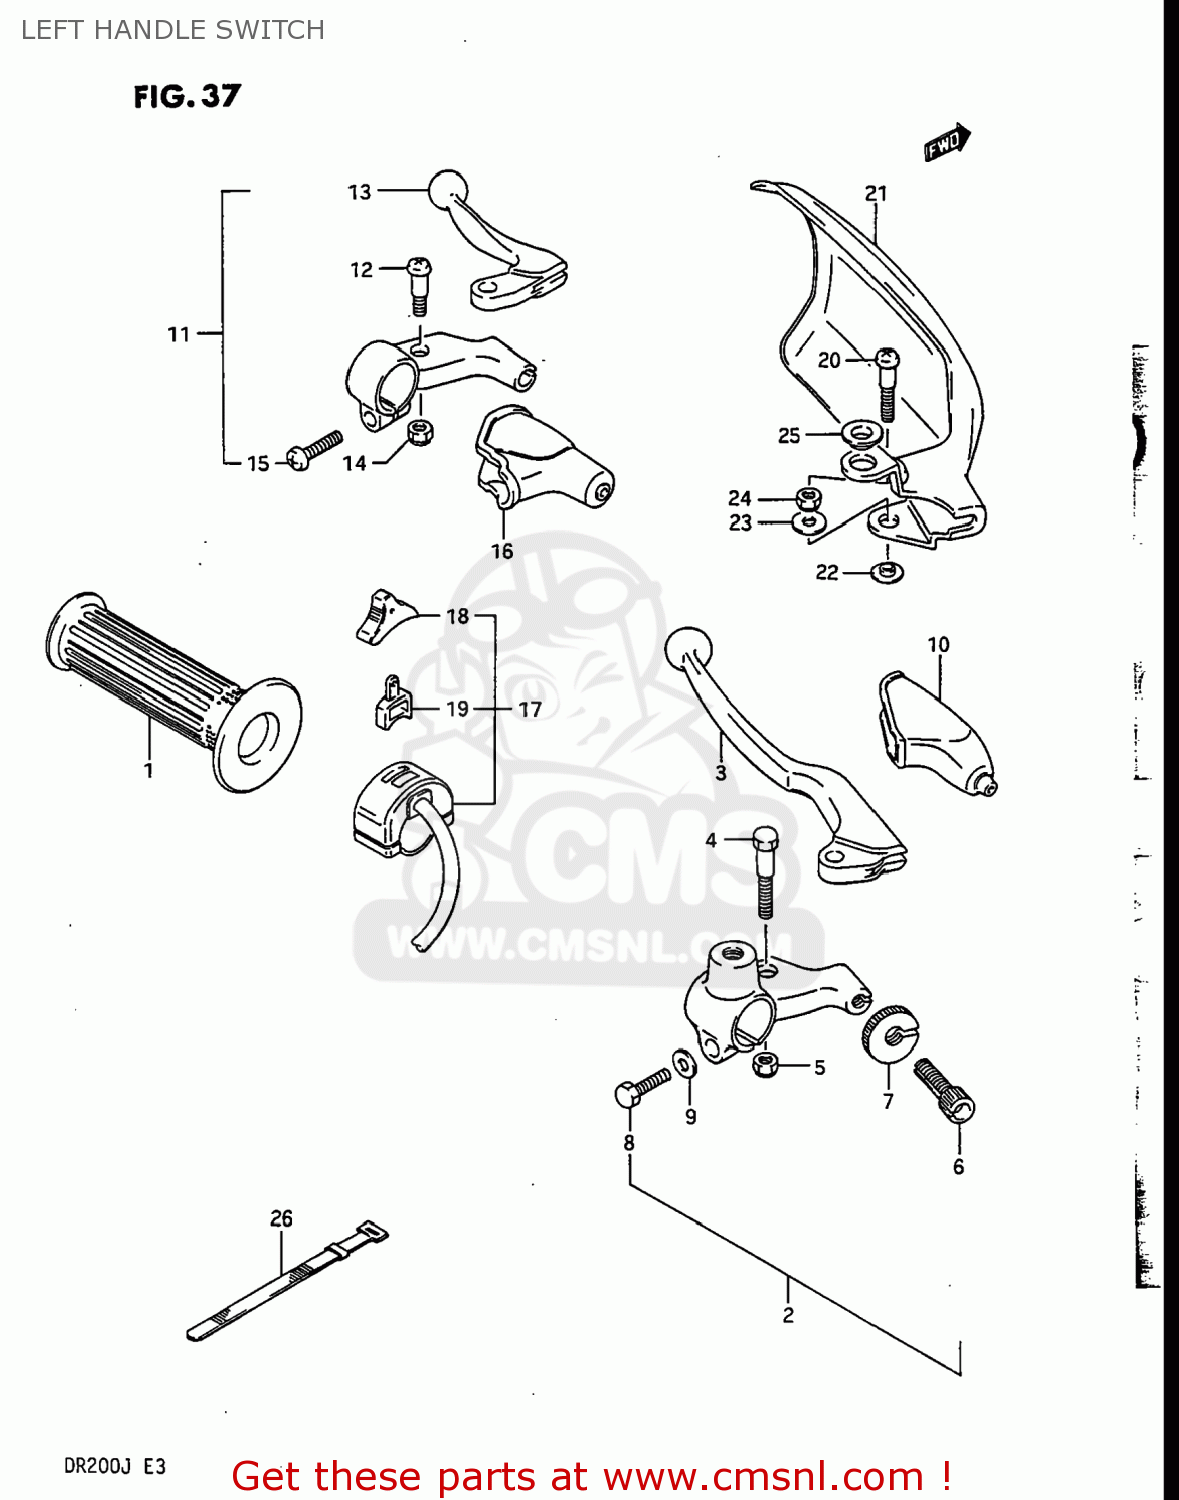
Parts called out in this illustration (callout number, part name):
1	GRIP,L
2	LEVER ASSEMBLY,CLUTCH
3	LEVER,CLUTCH
4	BOLT,LEVER PIVOT
5	NUT
6	ADJUSTER,CABLE
7	NUT,CABLE ADJUSTER LOCK
8	BOLT
9	WASHER
10	COVER,CLUTCH LEVER
11	LEVER ASSEMBLY,DECOMPRESSION
12	BOLT,LEVER
13	LEVER,DECOMP
14	NUT
15	SCREW
16	COVER,DECOMP LEVER DUST
17	SWITCH ASSY,LIGHTING
18	KNOB,LIGHTING & DIMMER
19	BLOCK,LIGHTING/DIMMER
20	BOLT,LEVER PIVOT
21	COVER,KNUCKLE,L
22	WASHER
23	WASHER(6.5X16X1.2)
24	NUT 6MM
25	WASHER
26	CLAMP(L:120)
